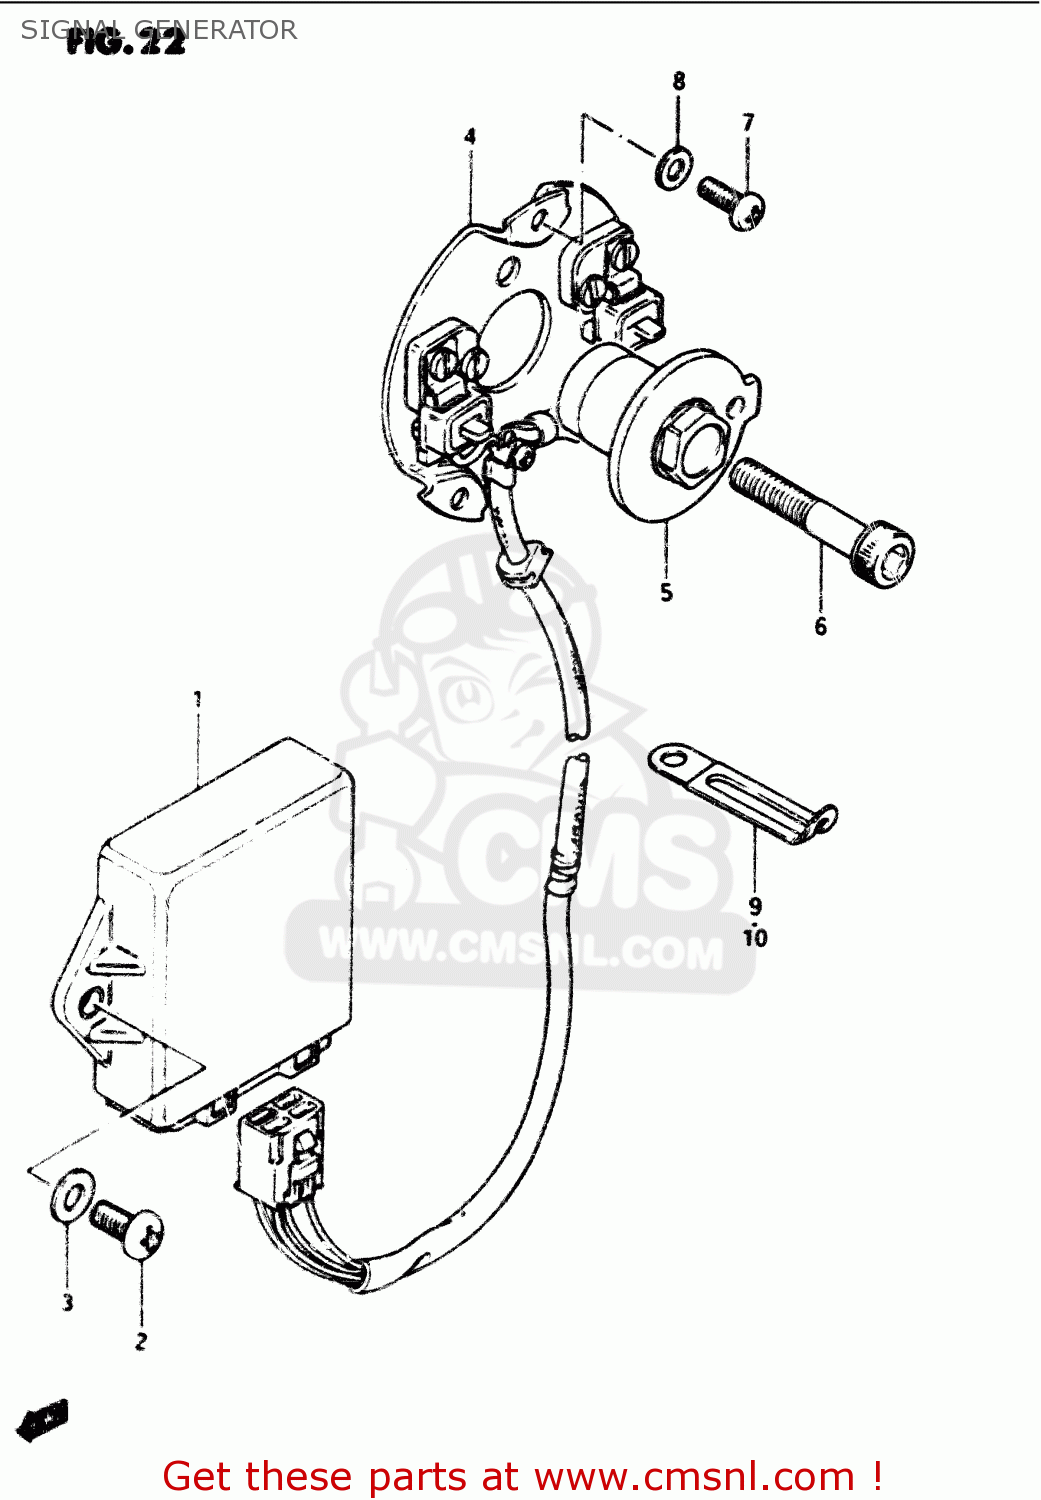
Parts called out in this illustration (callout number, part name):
1	IGNITOR UNIT,ESA
2	SCREW 6X12
3	WASHER
4	STATOR,SIGNAL GENERATOR
5	ROTOR,SIGNAL
6	BOLT
7	SCREW(5X12)
8	WASHER(5.5X10X0.8)
9	CLAMP L:35
10	CLAMP
